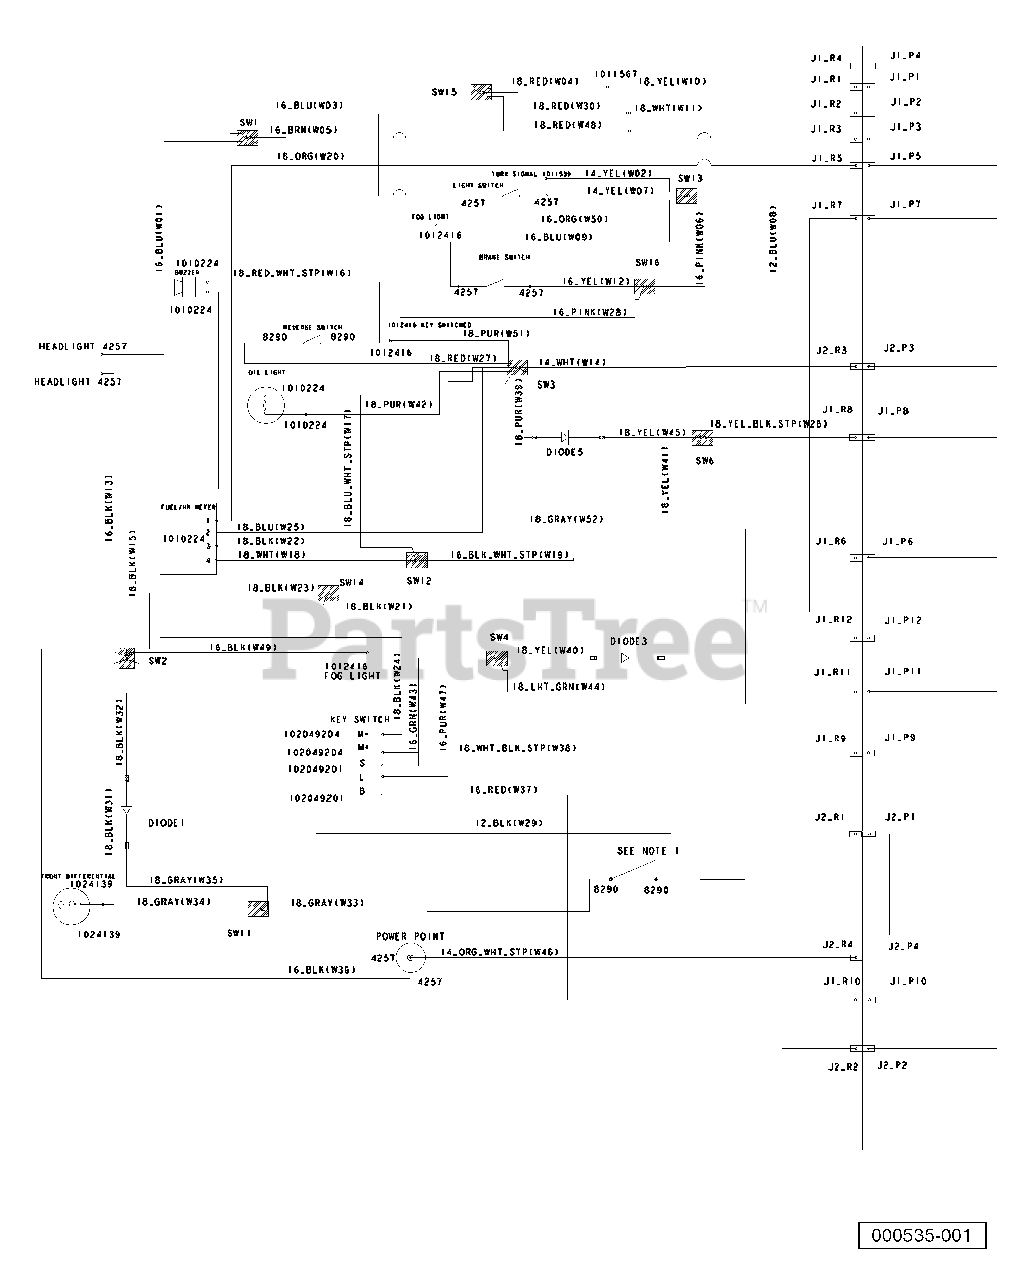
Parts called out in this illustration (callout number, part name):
1	Diode, General Purpose, 6.0a
2	Harness, Restyle Gas, Front
3	Harness, Restyle Gas, Rear
